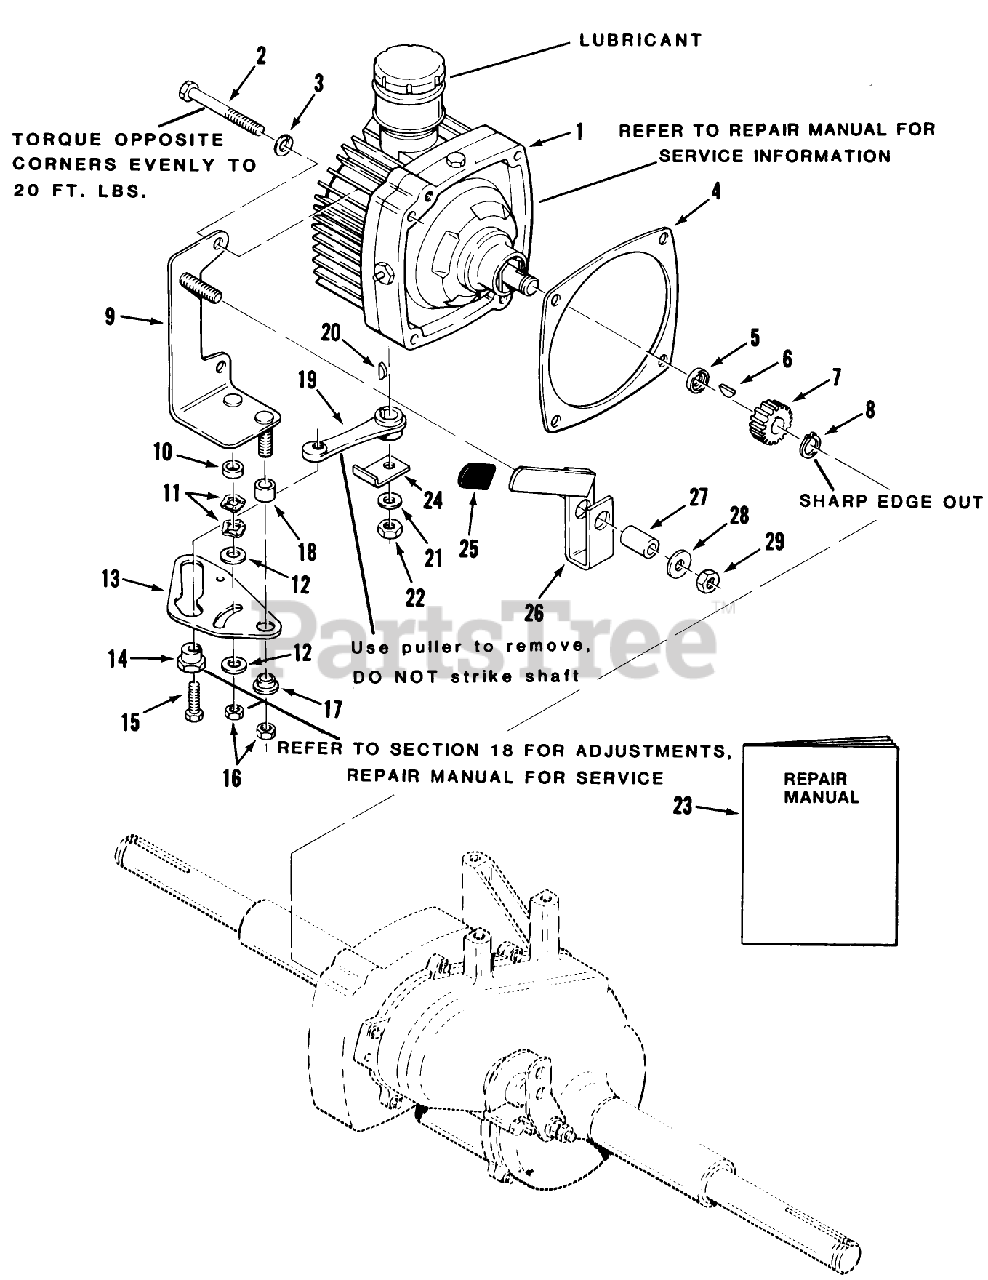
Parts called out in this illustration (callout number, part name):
1	Pump Motor (219024-Rebuilt)
2	Bolt 3/8-16 X 3
3	Lockwasher 3/8
4	Gasket
5	Spacer
6	Woodruff Key 1/8 X 1/2
7	Gear 12 Tooth
8	Snap Ring
9	Control Plate
10	Spacer (Short)
11	Washer-Spring
12	Washer-Friction
13	Cam-Speed Control
14	Eccentric Cam
15	Eslok Bolt 5/16-18 X 1
16	Lock Nut 3/8-16 Hi-Tensile
17	Spacer
18	Spacer (Long)
19	Cam Follower Arm
20	Woodruff Key 1/8 x 1/2
21	Washer 3/8 SAE
22	Eslok Nut 3/8-16
23	Automatic Trans. Repair Parts Service Manual
25	GRIP
26	ASS'Y-DUMP VALVE *B
27	SPACER
29	NUT-HEX, JAM
